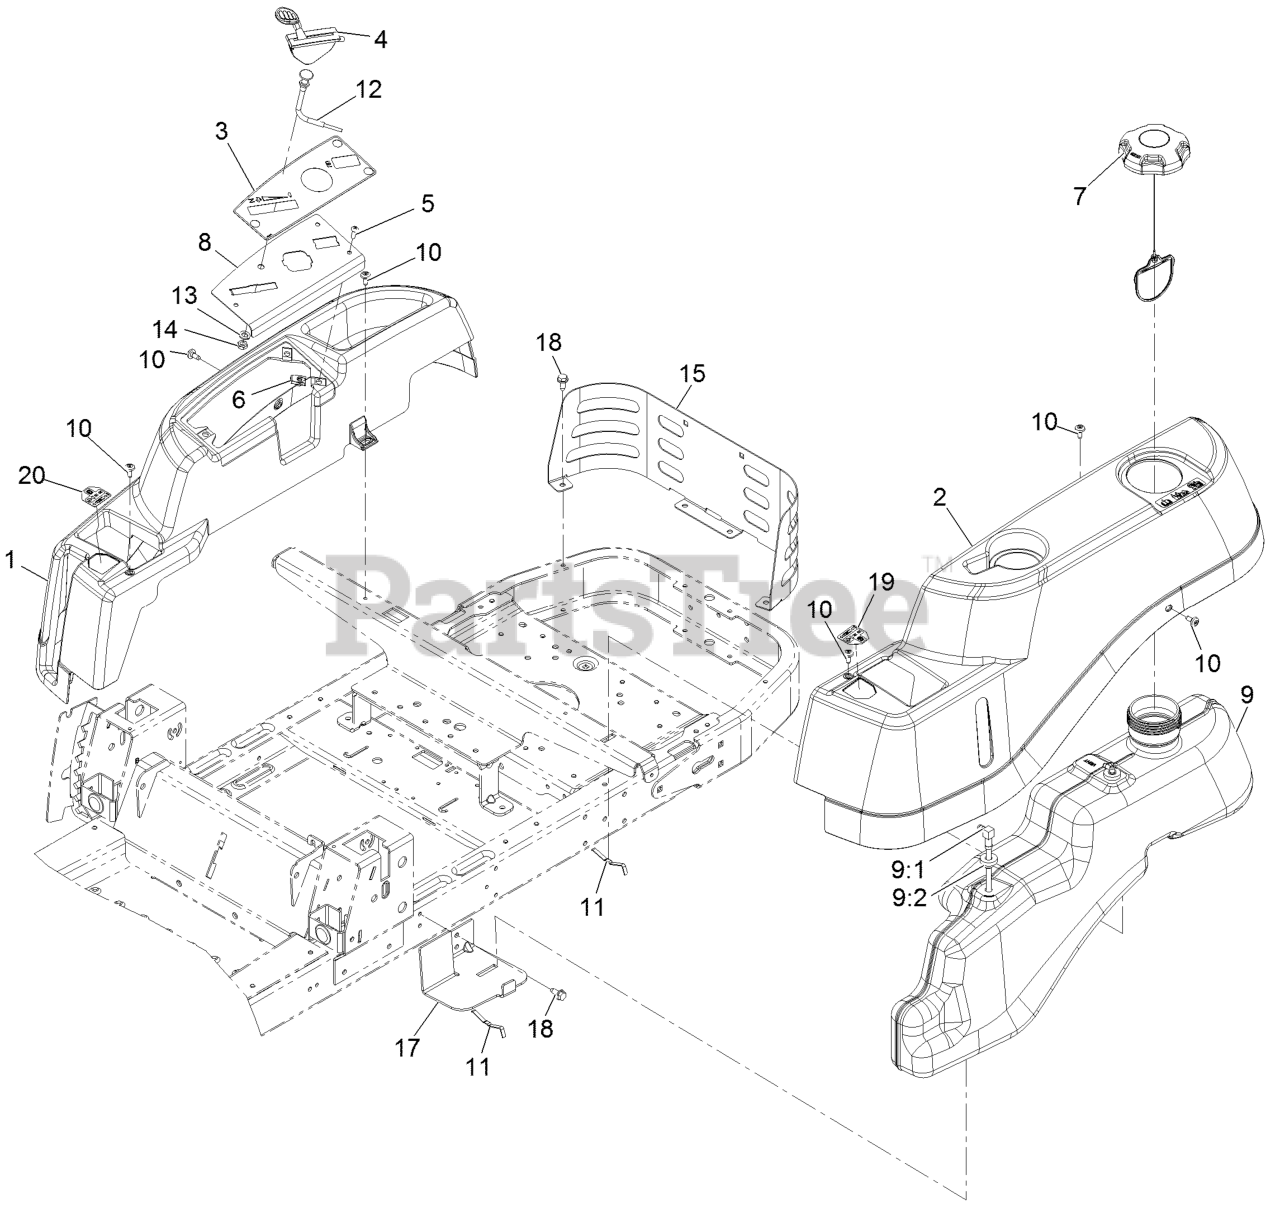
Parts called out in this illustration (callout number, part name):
3	DECAL-PANEL, CONTROL
4	CABLE-THROTTLE
5	SCREW-PRH
6	Nut-Retainer-Panel 1/4-20
8	PLATE-CONTROL
9	FUEL TANK ASM
9:1	CONNECTOR-ELBOW, 90 DEG
9:2	BUSHING
10	SCREW-SHOULDER
11	SPRING
12	CABLE-CHOKE
13	WASHER-LOCK
14	NUT-HJ
15	GUARD-REAR
17	SUPPORT-TANK, FRONT
18	Screw-HWH 5/16-18 X 3/4 Tf
19	DECAL-LEVER, CONTROL (LH)
20	DECAL-LEVER, CONTROL (RH)
